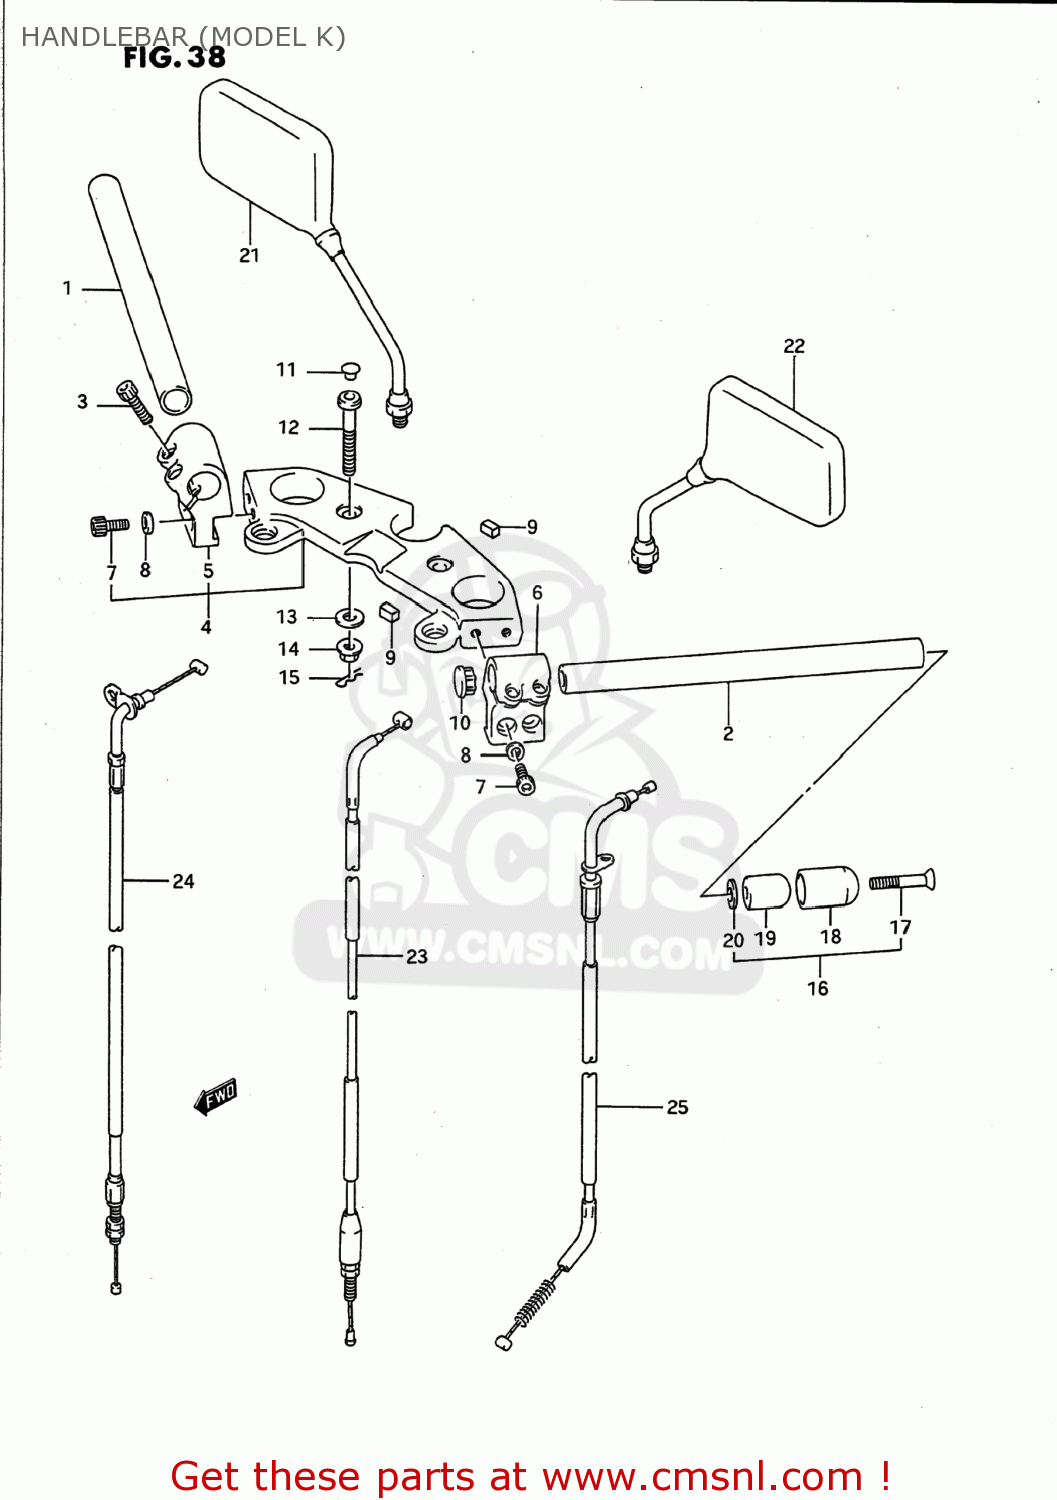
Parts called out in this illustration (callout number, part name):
1	HANDLEBAR,R
2	HANDLEBAR,LH
3	BOLT
4	HOLDER ASSEMBLY,HANDLEBAR
5	HOLDER,HANDLEBAR,RIGHT
6	HOLDER,HANDLEBAR,LEFT
7	BOLT
8	WASHER
9	CUSHION,HANDLE HOLDER
10	CAP,HANDLEBAR
11	CAP(OD:11)
12	BOLT(10X66)
13	WASHER
14	NUT 10MM
15	PIN 20X20
16	BALANCER SET,HANDLEBAR
17	SCREW
18	CAP,BALANCER
19	BALANCER,HANDLEBAR
20	SPACER,BALANCER
21	MIRROR ASSEMBLY,REAR VIEW
22	MIRROR ASSEMBLY,REAR VIEW
23	CABLE ASSY,CLUTCH
24	CABLE ASSY,THROTTLE
25	CABLE COMP,STARTER
